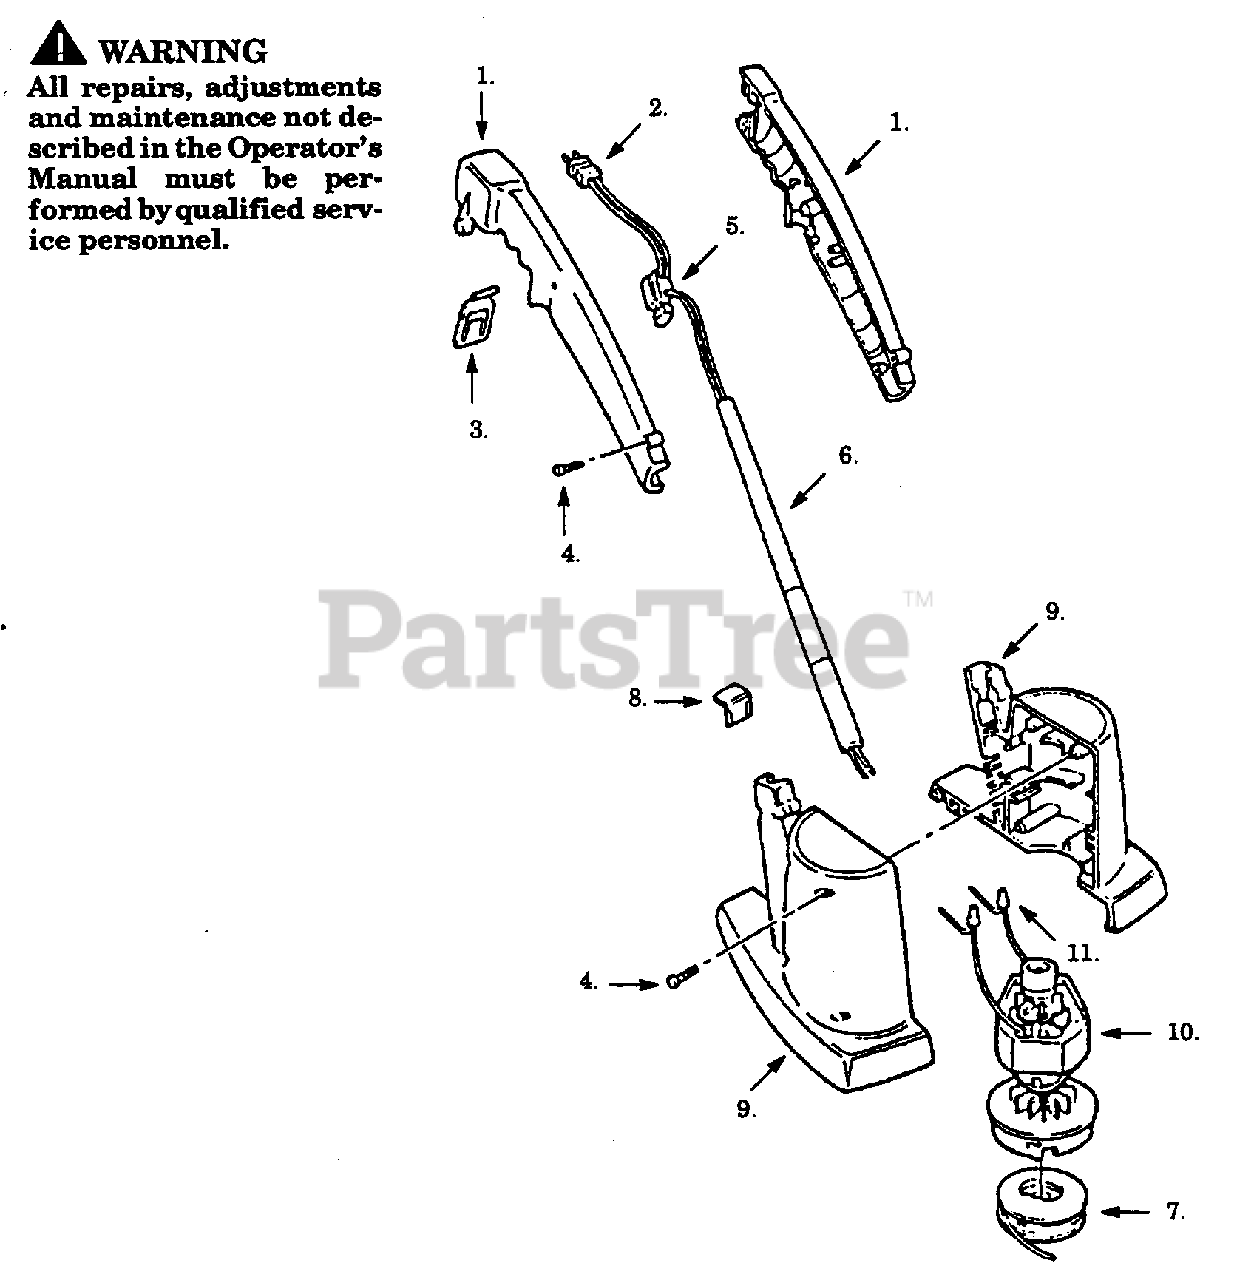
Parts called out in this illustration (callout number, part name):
1	Handle Set
2	Harness Ass'y.
3	Cord Retainer
6	Handle Tube
7	Spool w/Line
8	Line Cutter
9	Housing Set
10	Motor & Head Ass'y.
11	Terminal Cap
